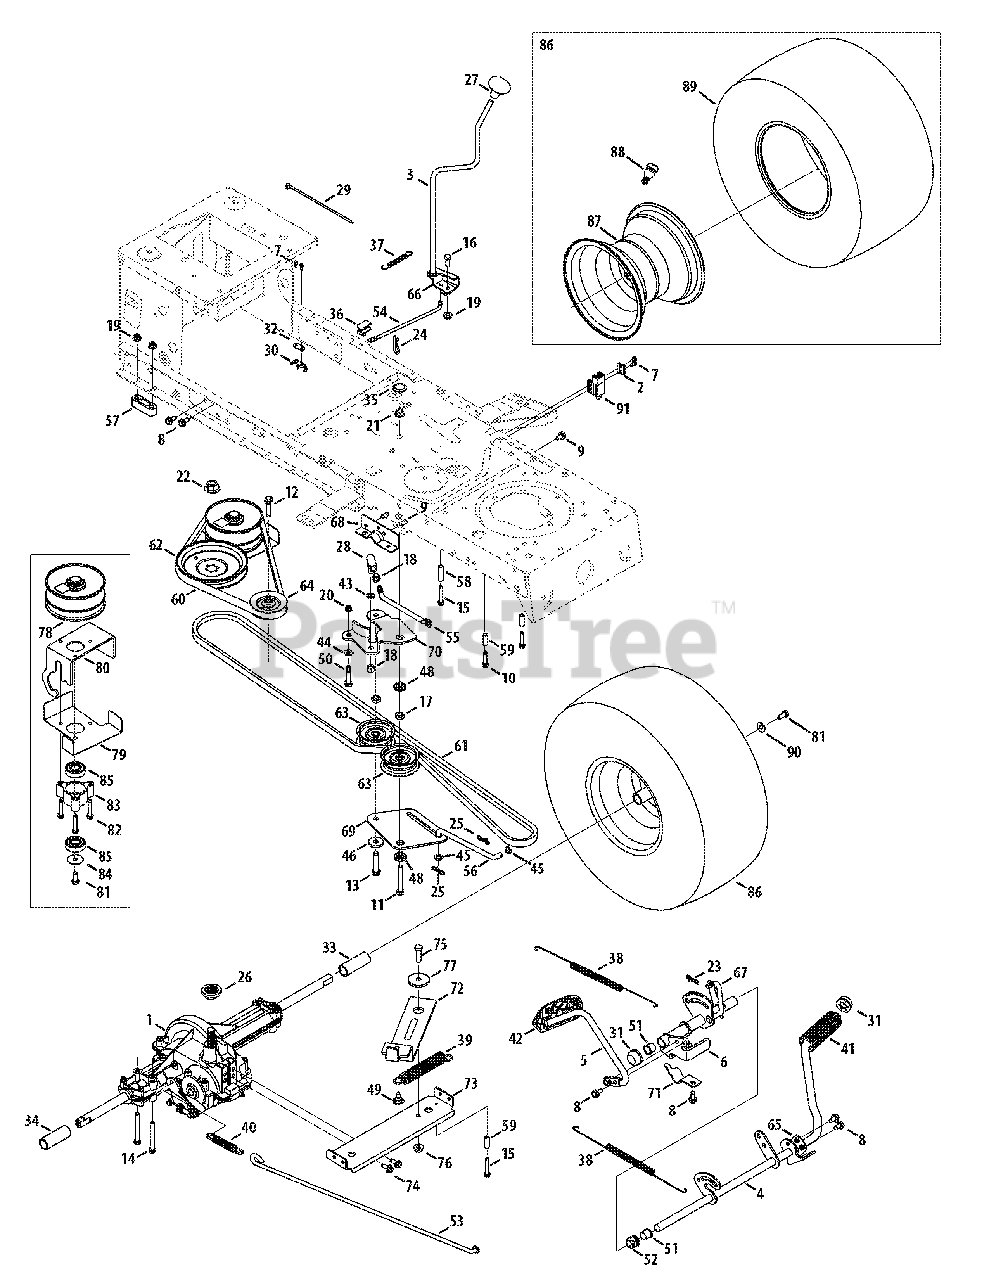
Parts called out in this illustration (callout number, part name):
1	Drive Assembly, AutoDrive
2	Plate Switch
3	Lever Assembly, Shift
4	Pedal Assembly, Drive
5	Pedal Assembly, Control
6	Bracket Assembly, Pedal
7	Screw, ab, #8-18, 0.500, Hxindwsh
8	Screw, tt, 5/16-18, .750, Hxindwsh
9	Screw, tt, 5/16-18, 0.625, Hxindwsh
10	Screw, tt, 1/4-20, 1.250, Hxindwsh
11	Hhcs, 3/8-16, 2.50, Gr5, Std
12	Screw, ttsems, 3/8-16, 1.500, Hxlwsh
13	Screw, ttsems, 3/8-16, 1.875, Hxlwsh
14	Hhcs, 5/16-18, 3.50, Gr5, Std
15	Screw, tt, 1/4-20, 1.625, Hxindwsh
16	Hhcs, 5/16-18, .75, Gr5, Std
17	Nut, jam, 7/16-20, Gr2
18	Nut, hex, 3/8-24, Gr5
19	Nut, flglk, 5/16-18, Grf, nylon
20	Nut, flglk, 1/4-20, Grf, nylon
21	Nut, flglk, 3/8-16, Grf, top Lk
22	Nut, flg, 9/16-18, Gr2
23	Pin, cot, 3/32, 1.0
24	Pin, cotter Int- .125 Dia
25	Pin, cotter, bow-Tie 72
26	Hub, Pulley, 5/8 Spline
27	Knob, Shift
28	Ball, joint
29	Cable, tie, 3/16 X .05 X 7.4
30	Switch, Springing, Short
31	Cap, push 5/8
32	Plate, Insulator Nut
33	Sleeve, .758 X .821 X 3.3125
34	Sleeve, .758 X .821 X 2.4375
35	Plug, deck Hole, 7/8
36	Bearing, Shift Rod
37	Spring, extension, .38 Od X 3.25 Lg
38	Spring, extension, .70 Dia X 12.00 Lg
39	Spring, extension, .97 Od X 6.18 Lg
40	Spring, extension, .59 Od X 4.00 Lg
41	Pad, foot, 4.0 Long
42	Pad, Control
43	Washer, lock, 3/8, Regular Duty
44	Washer, flat, .28 X .74 X .063
45	Washer, flat, .375 X .738 X .063
46	Washer, flat, .450x1.250x.164, Ht
48	Spacer, Drive, 1.00 X .38 X .38
49	Screw, Drive, .43x.29, Tt, 5/16-18
50	Screw, shld, .374 Dia. X 1.16 Lg.
51	Bearing, flg, .630 Idx .695 Od X .60
52	Bearing, hex Flg, .628 Id, split
53	Rod, brake,Trans
54	Rod, shift, 46"
55	Rod, adj, Idler, 3/8
56	Rod, trans, footPedalal Bypass
57	Spacer, T-Axle .68
58	Spacer, .260 X .372 X 1.420 Lg
59	Spacer, .260 X .375 X 1.030 Lg
60	Belt, v Typ, 5l X 40.9 Lg Poly
61	Belt, v Typ, 5l, 90.80, Poly
62	Pulley, v Typ, 7.25 Dia Spun
63	Pulley, Idler, flat 2.75 Od
64	Pulley, Idler, v-Type X 3.06
65	Bracket, Pedal, support
66	Bracket, Shift, adj
67	Plate, Bracket, reinforcement
68	Bracket, Pedal, frame Rh
69	Bracket, Idler, center Dbl
70	Bracket, Idler, dbl AutoDriveive Lt-5
71	Bracket, supt, Pedalal Stap
72	Bracket Assembly, Idler
73	Bracket Assembly, AutoDrive
74	Screw, tt, 5/16-18, 0.750, Hxindwsh
75	Hhcs, 3/8-16, 1.25, Gr5, Std
76	Nut, flglk, 3/8-16, Grf, nylon
77	Spacer, Drive, .8840 X .190
78	Pulley Assembly, var Spd, 4.75 Od
79	Keepr Assembly, belt
80	Bracket Assembly, vari Painted
81	Hhcs, 5/16-24, .750, Gr5, Lock
82	Screw, tt, 1/4-20, 1.500, Hxindwsh
83	Cup, Bearing
84	Washer, flat, .330 X 1.25 X .06, Ht
85	Bearing, ball, 17x40x12, 6203, Ds
86	Wheel, 20 x 8 x 8, 42"
87	Rim Assembly:8.0 X 7.0 X .750 Id
88	Valve, tubeless Air
89	Tire, 20 X 8 X 8 Sq Sh
90	Bell Washerer, .340 x .872 x .060
91	Switch Interlock
